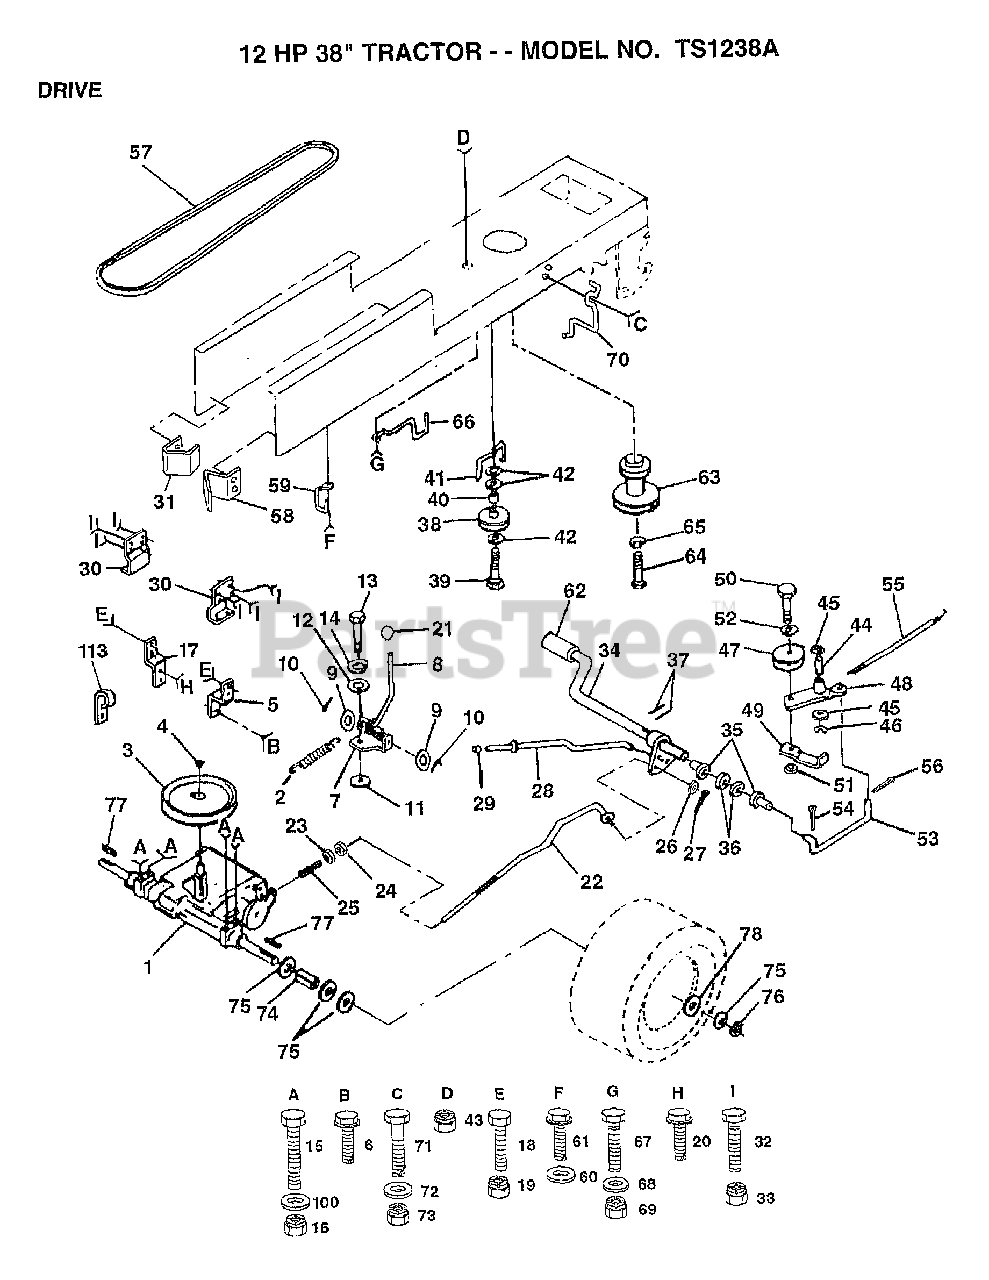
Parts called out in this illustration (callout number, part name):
3	PULLEY TRANS
5	STRAP TORQUE
6	SCREW
7	PLATE SHIFT LT
8	ROD SHIFTER
9	WASHER
10	PIN COTTER 1/8
11	WASH-SHFT PLT LT
12	WASHER LT
14	LOCKWASHER
15	BOLT
17	STRAP TORQUE
20	SCREW
21	KNOB T (1/2-HOLE)
23	NUT
24	NUT
25	SPRING ROD LT
26	WASHER
27	COTTER PIN
28	PARKING BRAKE ROD
29	PLUNGER CAP T
30	BRACKET LT
31	"KEEPER,BELT LH T"
32	BOLT
35	NYLON BEARING
36	WASHER LT
38	PULLEY.IDLER.FLAT
39	BOLT
40	SPACER T
41	BELT KEEPER LT
42	WASHER
44	"LY, BEARING"
45	WASHER LT
46	KLIP RING
48	ARM IDLER
49	RETAIN BELT
52	WASHER
53	"LINK, CLUTCH T"
54	COTTER PIN
55	"SPRING, RETURN LT"
56	COTTER PIN
57	BELT-V.90.0.GD.DR
58	"KEEPER,BELT RH T"
60	WASHER
61	SCREW
62	PEDAL COVER T
63	PULLEY.ENGINE
64	BOLT
65	LOCKWASHER
66	KEEPER.BELT.ENG.L
67	BOLT
68	WASHER
70	KEEPER BELT ENG
71	BOLT
72	WASHER
74	SPACER LT
75	WASHER
76	E-RING LT
77	SQUARE KEY
78	WASHER
100	WASHER
113	CLIP T
